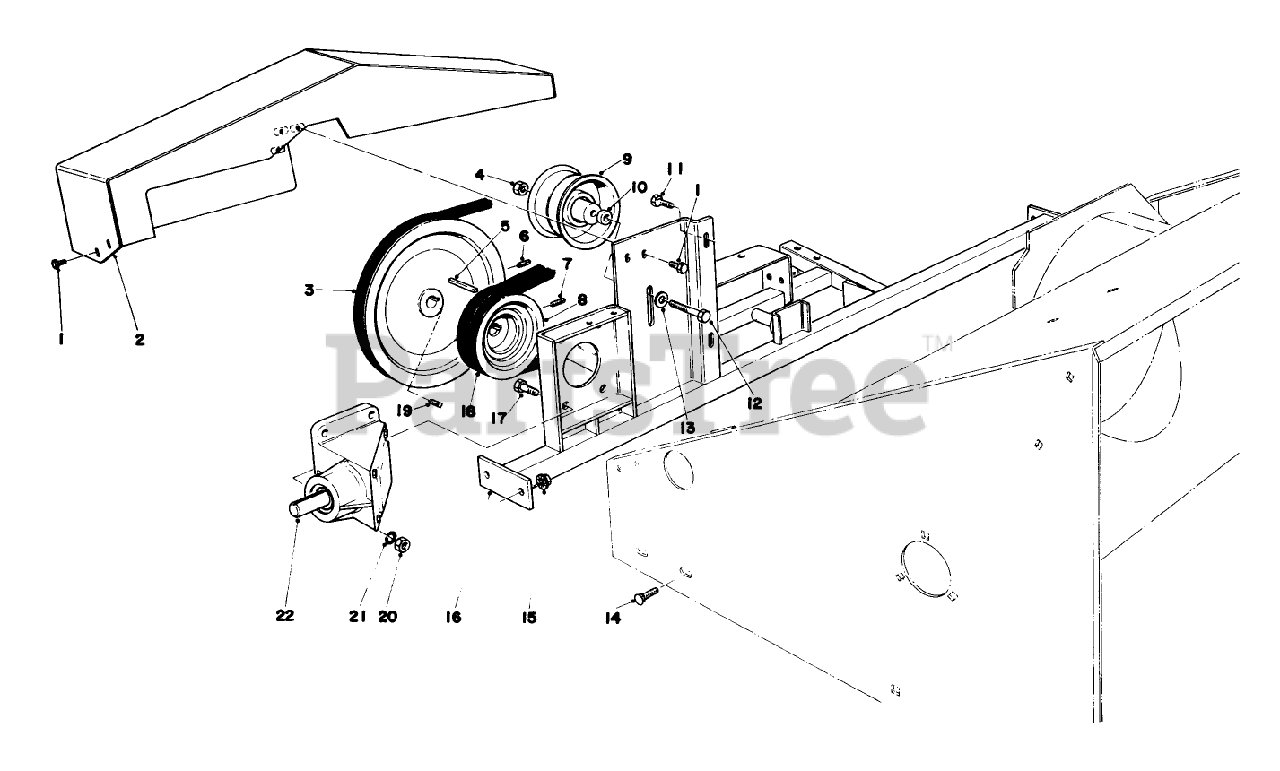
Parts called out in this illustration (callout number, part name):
1	SCREW-HHF
2	BELT SHIELD WA
3	SHEAVE 60014
4	NUT-LOCK, CONE
6	SCREW-SQH
7	SCREW-SET, SQH
8	PULLEY
9	Idler Pulley
10	IDLER SPACER
11	SCREW-HH
12	SCREW-HH
13	WASHER-FLAT
14	SCREW-CARR
15	NUT-HHF, WHIZ
16	Cross Brace
17	SCREW-HH
18	V-BELT
19	SCREW-SET, SQH
20	NUT-HEX
21	WASHER-LOCK
22	Gear Box Assembly
